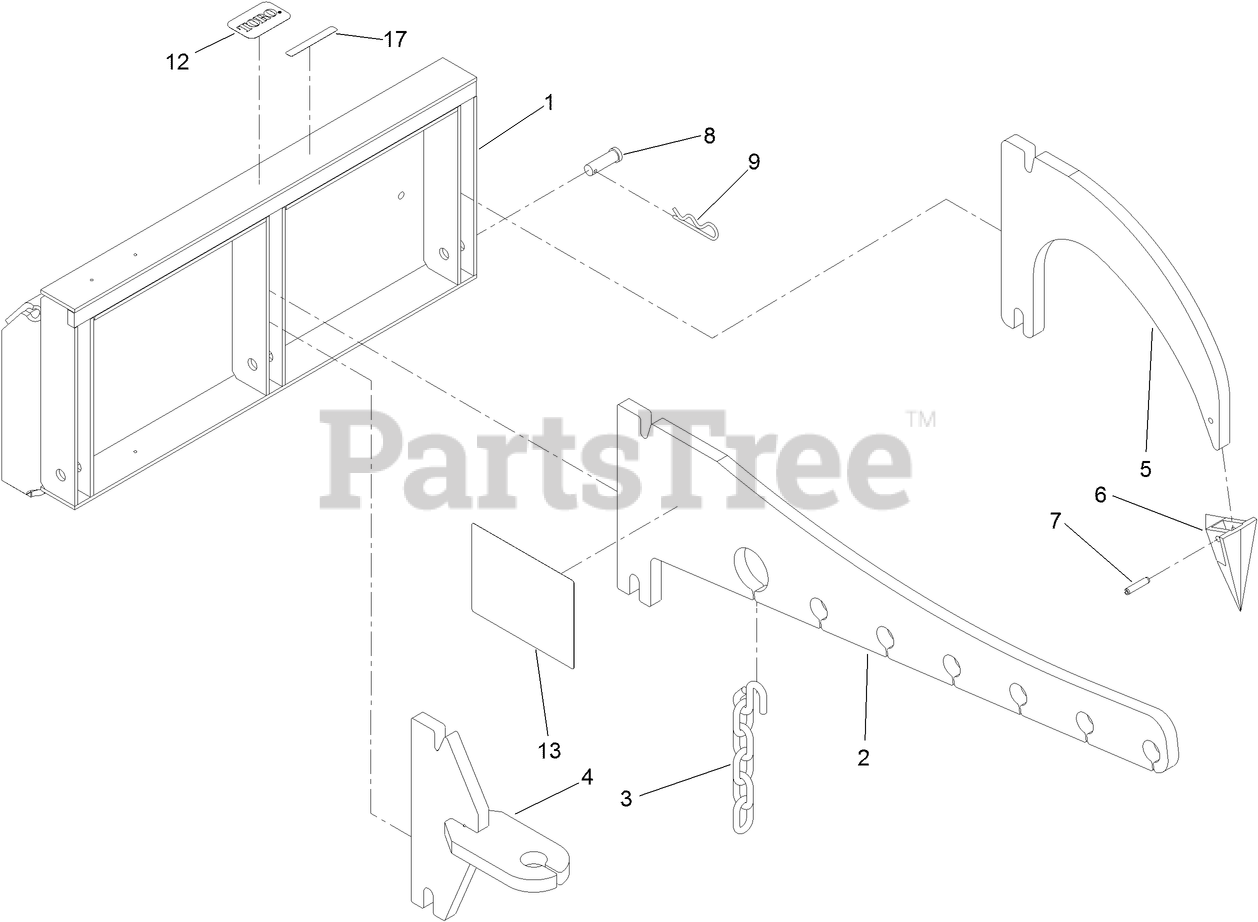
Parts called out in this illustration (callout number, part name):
1	CARRIER TOOL ASM
3	CHAIN-LIFT
4	TOW BAR ASM
5	PLATE-TYNE
6	POINT-SPEAR
7	PIN-SPRING
8	PIN-CLEVIS
9	PIN-HAIR
12	DECAL
13	DECAL-RATING, LOAD
17	DECAL-WARNING
